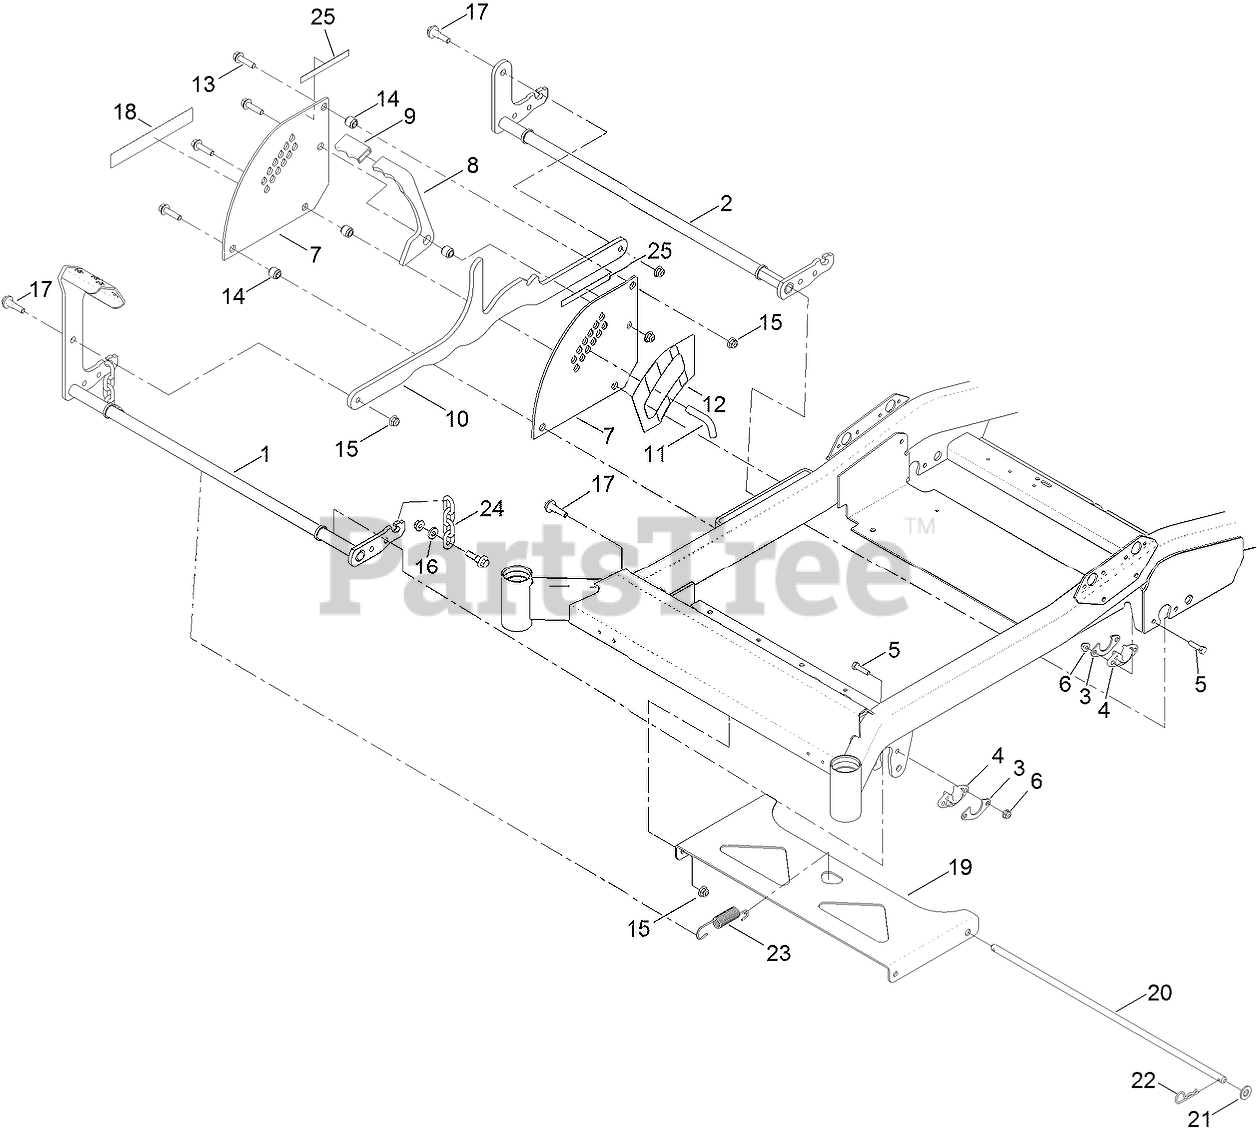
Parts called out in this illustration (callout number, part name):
1	PIVOT-FRONT
2	PIVOT-REAR
3	GUSSET-LIFT, DECK
4	BUSHING-FLANGE
5	SCREW-HH
6	NUT-HF, NI
7	PLATE-DECK, LIFT
8	LOCK-TRANSPORT, HOC
9	GRIP-FLAT
10	LINK-HOC
11	PIN-HOC
12	DECAL-HOC
13	SCREW-HHF
14	SPACER-STEP, DOUBLE
15	NUT-HF, NI
16	SPACER
17	BOLT-SHOULDER
19	PAN-DECK, PIVOT
20	ROD-DECK, PIVOT
21	WASHER-FLAT
22	PIN-COTTER
23	SPRING-EXTENSION
24	CHAIN-DECKLIFT
25	PAD-RUBBER
